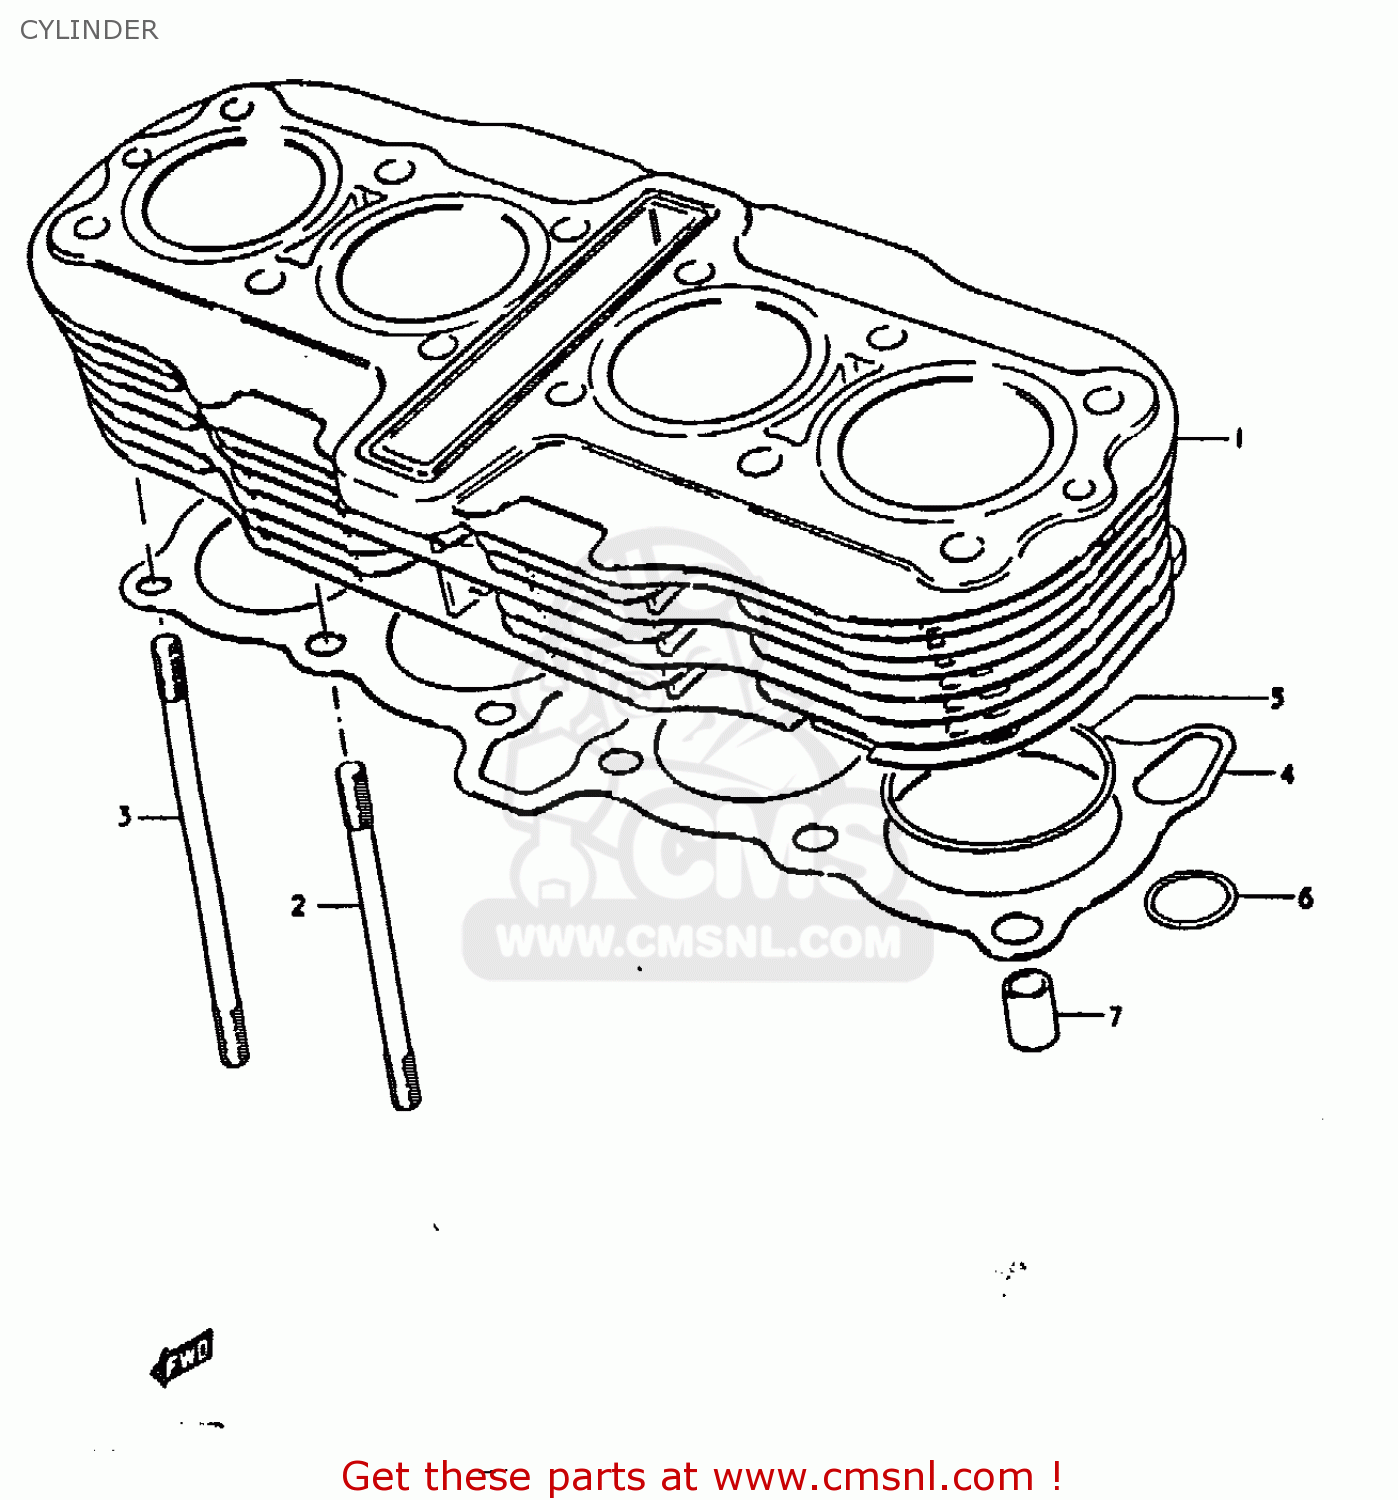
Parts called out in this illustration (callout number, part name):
1	CYLINDER
2	BOLT,STUD
3	STUD
4	GASKET,CYLINDER (MCA)
5	O RING(D:2,ID:74)
6	O RING(D:3.05)
7	PIN
